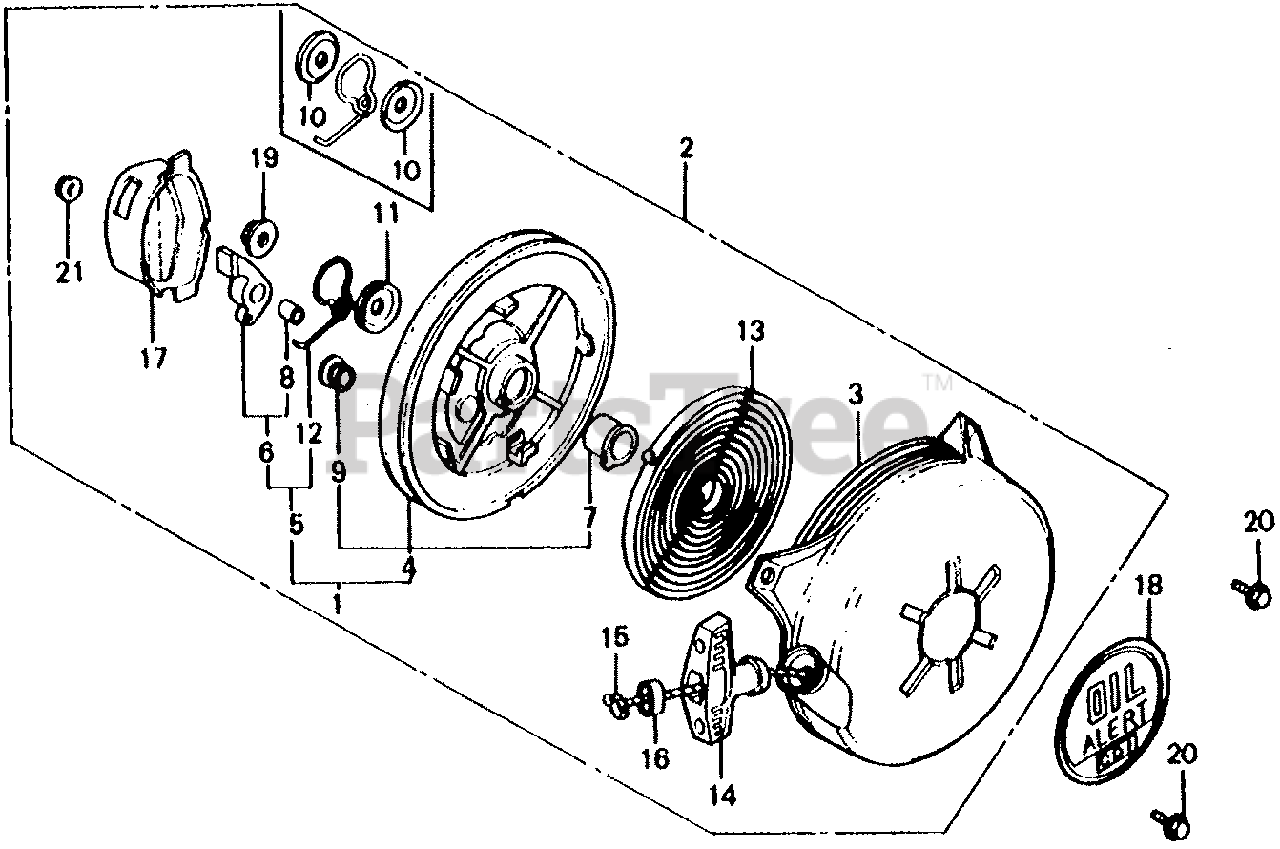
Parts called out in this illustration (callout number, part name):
1	REEL, STARTER
2	STARTER ASSY., RECOIL *R8* (BRIGHT RED)
3	CASE, STARTER *R8* (BRIGHT RED)
4	REEL, STARTER
5	RATCHET KIT
6	RATCHET KIT
6	RATCHET
7	BOSS, REEL
8	BUSH, RATCHET
9	BUSH, REEL STARTER
10	PLATE, FRICTION
11	PLATE, FRICTION
12	RATCHET KIT
12	SPRING, FRICTION
13	SPRING, RETURN
14	GRIP, STARTER
15	ROPE, STARTER (#5X55")
16	SUPPORT, GRIP
17	COVER, REEL STARTER
19	NUT, SELF-LOCK (8MM)
20	BOLT, FLANGE (6X8)
21	NUT, FLANGE (5MM)
